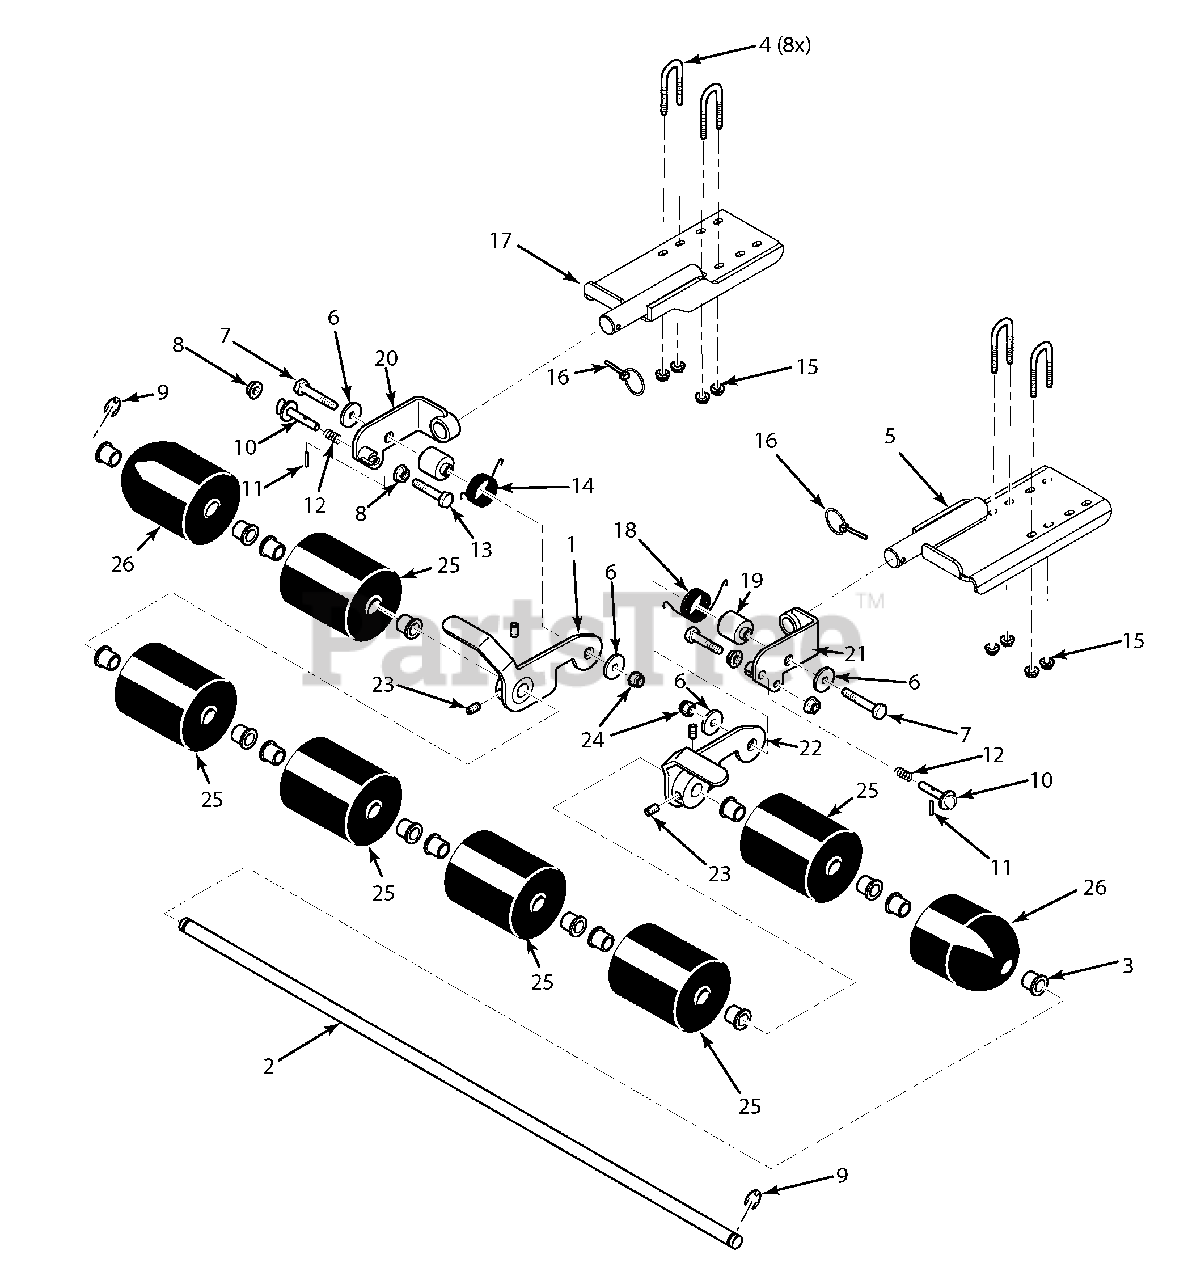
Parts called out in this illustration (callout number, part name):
1	Hinge Weldment, L.H.
2	Roller Shaft
3	Bushing, .752 Oilite
4	U-Bolt, 1/4-20 x 3/4"
5	Mounting Bracket Weldment, SCZ LH.
6	Flatwasher, 3/8-.406 x 1-1/2" 7 Gauge
7	Bolt, Hex Head 3/8-16 x 2-3/4"
8	Nut, Serrated Flange 3/8-16
9	Retaining Ring, .750 External "E"
10	Pin, Lift Latch
11	Pin, Slotted Spring .156 x 3/4"
12	Spring, Lock Pin
13	Bolt, Hex Head 3/8-16 x 2-1/2"
14	Spring, Torsion L.H.
15	Nut, Serrated Flange 1/4-20
16	Quick Pin, .188 Dia.
17	Mounting Bracket Weldment, SCZ R.H.
18	Spring, Torsion R.H.
19	Hub, Striper
20	Pivot Weldment, L.H.
21	Pivot Weldment, R.H.
22	Hinge Weldment, R.H.
23	Set Screw, 3/8-16 x 1/2"
24	Nut, Elastic Stop 3/8-16
25	Roller Assembly
26	Roller Assembly, Striper End
27	Hinge Weldment, L.H.
